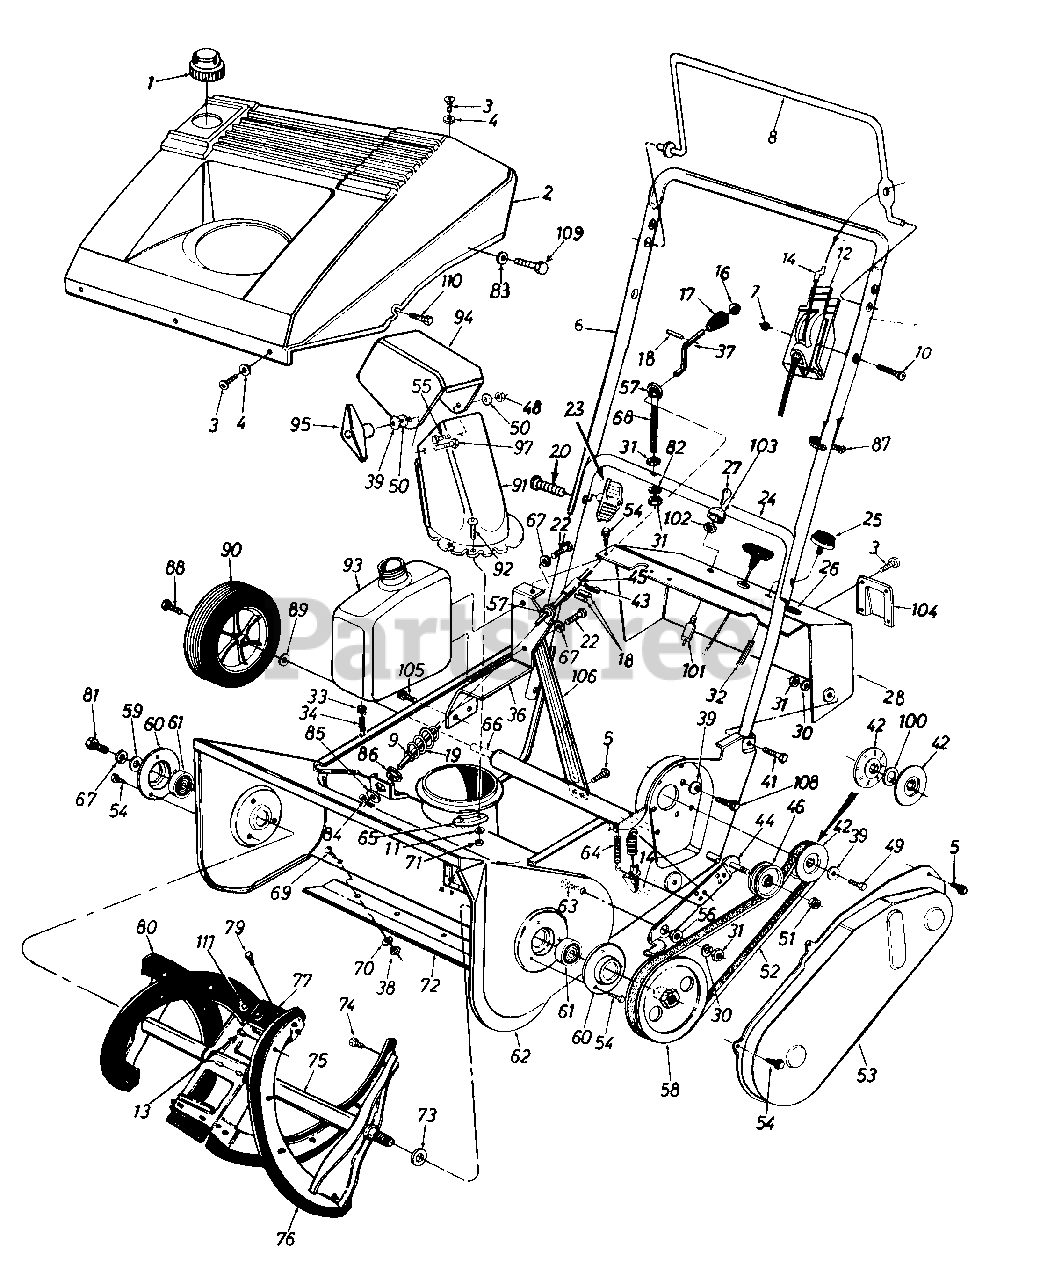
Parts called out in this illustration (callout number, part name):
1	Gas Tank Cap
2	Shroud
3	Hex B-Tap Scr. #10 x .38" Lg.
4	Fl-Wash .203" I.D. x .41"
5	Hex L-Wash. Hd. AB-Tap 1/4 x .62" Lg.
9	Fl-Wash .385" I.D. x .62"
10	Oval C-Sunk Mach. Scr.
11	Fl-Wash .281" I.D. x .5" O.D.
12	Throttle Body
13	Pop Rivet .187" Dia.
14	Clutch Cable 35" Lg.
16	Push Cap 3/8" Rod
17	Knob - 3/8" Dia. Hole
18	Roll Pin 3/8" Dia. x .63" Lg.
19	Lower Chute Crank Ass'y.
20	Curved Hd. Bolt 5/16-18 x 2" Lg.
22	Hex Bolt 1/4-20 x .5" Lg.
23	Handle Knob
26	Plastic Plug
31	Hex Nut 5/16-18 Thd.
32	Primer Hose - 9" Lg.
33	Hose Clamp - 1/2" O.D.
34	Gas Line 26" Lg.
36	Gas Tank Support Brkt.
38	Hex Jam Nut 1/4-20 Thd.
39	Bell-Wash. 5/16" I.D. x .937" 0 D.
41	Hex Bolt 5/16-18 x 1.5" Lg.
42	3/8" "V"-Pulley Half .625" I.D. x 6.0" O.D.
43	Cotter Pin 3/32" Dia.
46	Fl-Idler w/Flanges 2.12" O.D.
48	Hex L-Nut 5/16-18 Thd.
49	Hex Bolt 5/16-24 x .75" Lg.
50	Fl-Wash .344" I.D. x 1.25"
51	Hex Patch L-Nut 3/8-24 Thd.
52	"V"-Belt
54	Hex B-Tap Scr. 1/4" x .38" Lg.
55	Carriage Bolt 5/16-18 x .75"
56	Shld. Spacer .50" Dia. x .27"
57	Plastic Bushing .38" I.D.
58	1/2" "V"-Pulley 1/2-20 L.H. x 6"
59	Fl-Wash. 1/4" I.D. x .93" O.D.
64	Extension Spring 1.12" Lg
65	Chute Flange Keeper
66	Wheel Axle 20 6" Lg
67	L-Wash 1/4" I.D.
68	Eyebolt
69	Carriage Bolt 1/4-20 x 50"
70	Fl-Wash .281" I D. x 73"
71	Hex L-Nut 1/4-20 Thd.
72	Shave Plate
73	Fl-Wash 510" I D x 1 0" 0 D.
74	Hex Wash B-Tap Scr. 1/4 x .62" (Spec)
76	Rubber Spiral - L.H.
77	Rubber Paddle
79	Hex Wash B-Tap Scr. #10 x .62" Lg.
80	Rubber Spiral - R H.
81	Hex Wash TT-Tap CI-Scr. 1/4-20 x 75" Lg
82	Saddle Wash 32" I D
83	Fl-Wash .218" I.D x 62" O.D.
84	Cotter Pin 3/32" Dia x .75"
85	Fl-Wash .406" I.D x 1.25"
86	Hex Bushing 385" I D
87	Cable Tie
88	Hex Tap Scr. 3/8-24 x .5" Lg
89	Fl-Wash .510" I.D x .75"
90	7" Wheel & Tire Ass'y.
91	Lower Chute
92	Truss Mach. Scr. 1/4-20 x 75"
93	Fuel Tank - Two Qt.
94	Upper Chute
95	Knob
97	Carriage Bolt 5/16-18 x 1"
100	Fl-Wash .635" I.D. x .93" 0 D
101	Key Switch
102	Ignition Switch Nut 5/8-32 Thd.
103	Ignition Switch Cap
104	Choke Cover
105	Hex Wash. Hd. Tap Scr. 1/4-.5" Lg.
109	Hex B-Tap Scr. #10 x .38" Lg.
110	Hex Wash. Hd. Tap Scr 1/4-20 x 1" Lg
111	Torx AB-Tap Scr. 1/4 x .62" Lg.
